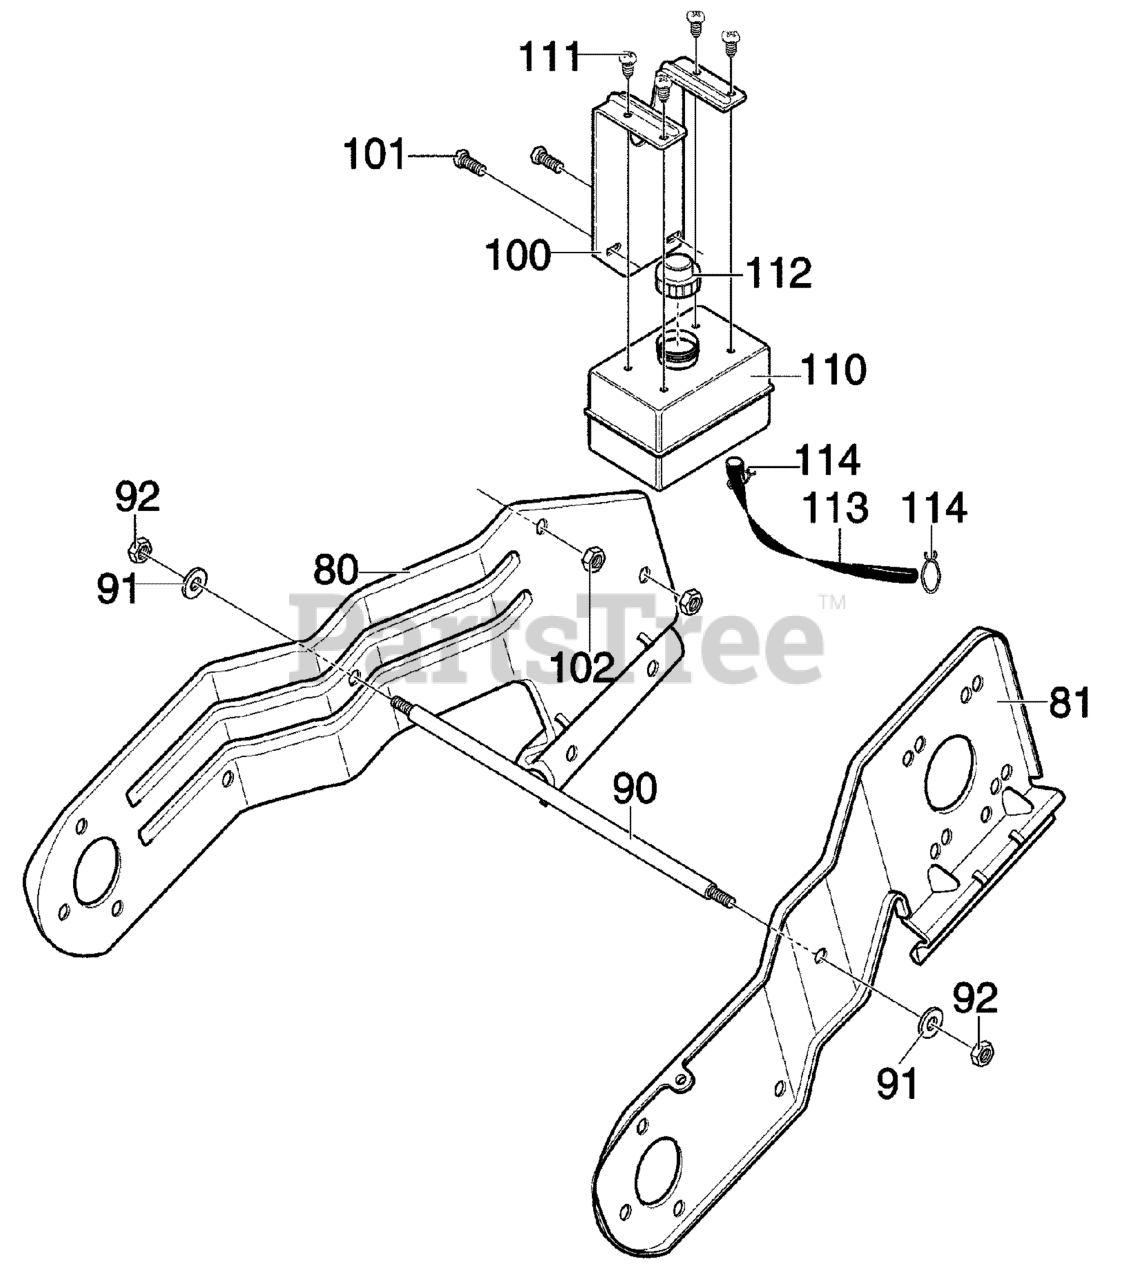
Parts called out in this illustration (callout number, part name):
80	FRAME SIDE SUPPORT RH
81	FRAME SIDE SUPPORT LH
90	ROD, SUPPORT
91	WASHER
92	NUT, 3/8-16 HEX
100	BRACKET, GAS TANK
101	SCREW, 1/4-20X.75
102	NUT, 1/4-20
110	TANK, FUEL
111	SCREW, 1/4-14X.88
112	CAP, GAS-BLACK
113	TUBING 11.50 IN.
114	CLAMP, FUEL LINE
